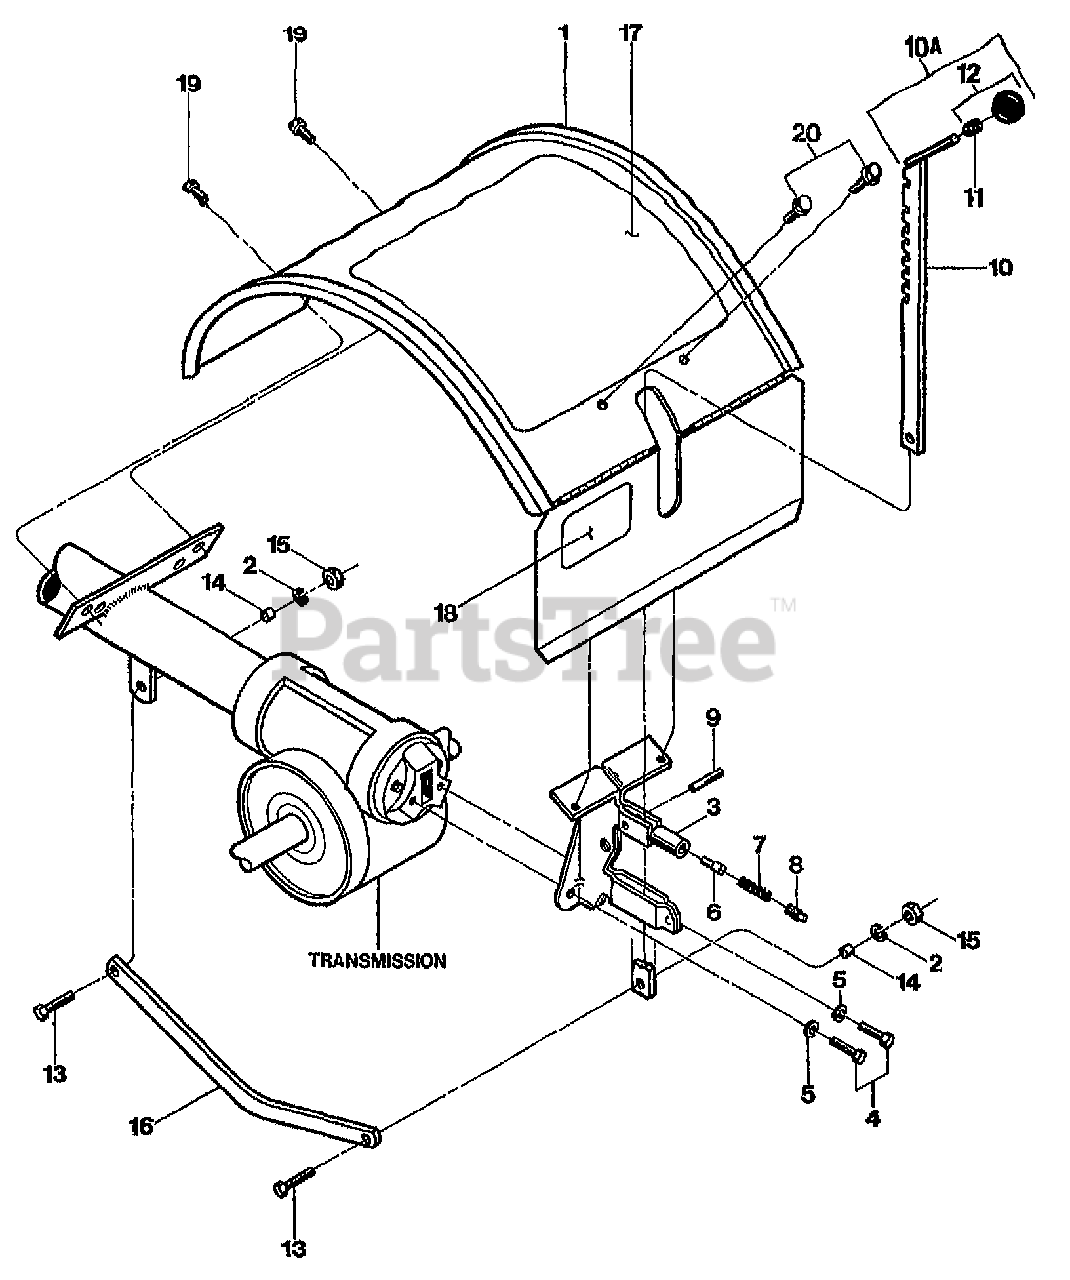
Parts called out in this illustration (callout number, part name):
1	HOOD W/DECALS P/J (Tine cover w/ hinged flap; Inc. 17 & 18.)
2	WASHER-LK .375 @ DEPL
3	KIT-REAR HOOD BRKT (Hood & depth reg., Inc 9)
4	SCR-HHC 5/16-18X.75 GR 5 ZP (Bracket to rear bearing cap.)
5	WASHER-LK .312 ZP
6	PLUNGER (Depth reg. locking.)
7	SPRING .406 X 1.25 (Depth reg. plunger.)
8	PLUG-PIPE 1/4 NPT
9	PIN-ROLL .25 X 1 (Spiral)
10	BAR ASSEMBLY (Not available separately, see #10A)
10A	DEPTH REGULATOR W/KNOB (depth adj.; Inc. 10- 12)
11	RING-TOLERANCE .5325 ID
12	KNOB-CONTROL (Depth reg. Inc. #11)
13	SCR-HH 3/8-16X1.25
14	BUSHING-.5X.375X.3 (Spacer, Drag Bar)
15	NUT-HEX 3/8-16 ZP
16	DRAG BAR-BENT (Depth reg.)
17	DECAL-HOOD INST
18	DECAL-TB JR LOGO
19	SCR-HWH 5/16-18 X .5 STH
20	SCR-HWH 1/4-20 X .5 STH
